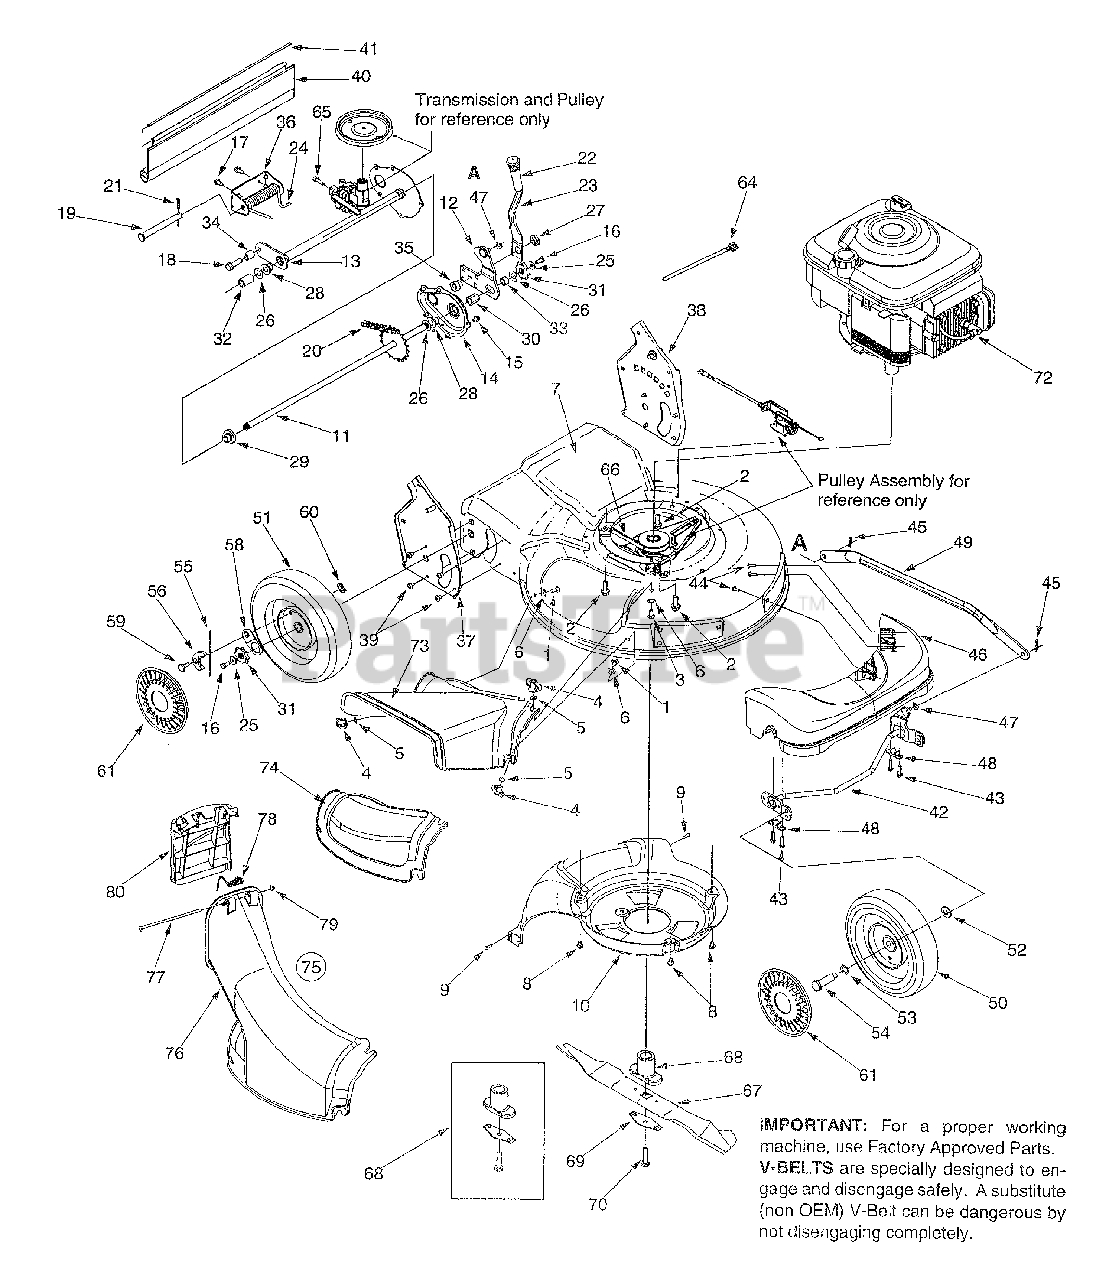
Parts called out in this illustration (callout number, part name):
1	Carriage Screw 1/4-20 x .62
2	TT Screw 3/8-18:1.00
3	Screw 1/4-20 x .750
4	Wing Nut 1/4-20
5	Push Nut .25 I.D. x .50 O.D.
6	Flat Washer .334 I.D. x .62 x .03
8	TT Screw 1/4-20 x .375
9	HL Screw 1/2-14 x .750
10	Baffle
11	Rear Axle Ass'y
16	Cap Screw HH 1/4-20 x .620
17	AB Scr. 1/4-14 x .625
18	Scr. 3/8 116 x .25
19	Clevis Pin .50 Dia. x 4.82
20	Chain-Endls. #48 .500P x 24
21	Cotter Pin .1250.D. x .75
23	Spring Lever
24	Torsion Spring
25	Bell Wash. .285 x .75 x .082
26	Fl. Wash. .508 I.D. 1.000 x.020
27	Nut Shld. .825 Dia. x. 165
28	Hx. Flg. Brg. .506 I.D. x .590
29	Hx. Flg. Brg. .506 I.D. x .715
30	Hx. Slv. Brg. .504 I.D. x .830
31	Wheel Rachet
32	Spacer .550 I.D. x /750 O.D.
33	Spacer .5 I.D. x .70 O.D. x 38
34	Spacer .385 x .624 x .700
35	Shld. Spacer .385 I.D. X .715
40	Trail Shield
41	Trail Shield Wire
43	Hx Scr. Wash Hd. Hi.-Lo.
44	Scr. Torx, Truss Hi.-Lo.
45	Cotter Pin .072 x 1.12 Lg.
46	Front Axle Cover, Black
47	Bowed Washer
48	Bush. Block .505 Dia. x .62
50	Wheel 8 x 2
51	Wheel 9 x 2
52	Spring Washer
53	Wave Wash .510 x .750 x .017
54	Shldr Scr .498 x 1.445 x 3/8-16
55	Spring, Ratchet, Plastic
56	Pawl: RH.
58	Ratchet Pawl Plate
59	Shoulder Scr. .340 x .285
60	Top Lock Tab Weld Nut 1/4-20
61	Hubcap: Rad. Spoke Beige
64	Cable Tie
65	Hex Screw 5/16-18
66	V-Belt
67	21" Mulching Blade
68	Blade Adapter Kit
69	Blade Bell Suport
70	Hex Bolt 3/8-24 x 2.5" Lg.
72	Spark Plug Insulator
73	Side Discharge Chute
74	Mulch Cover
75	Rear Chute Ass'y w/Door
76	Discharge Chute
77	Pivot Rod
78	Torsion Spring
80	Chute Door
